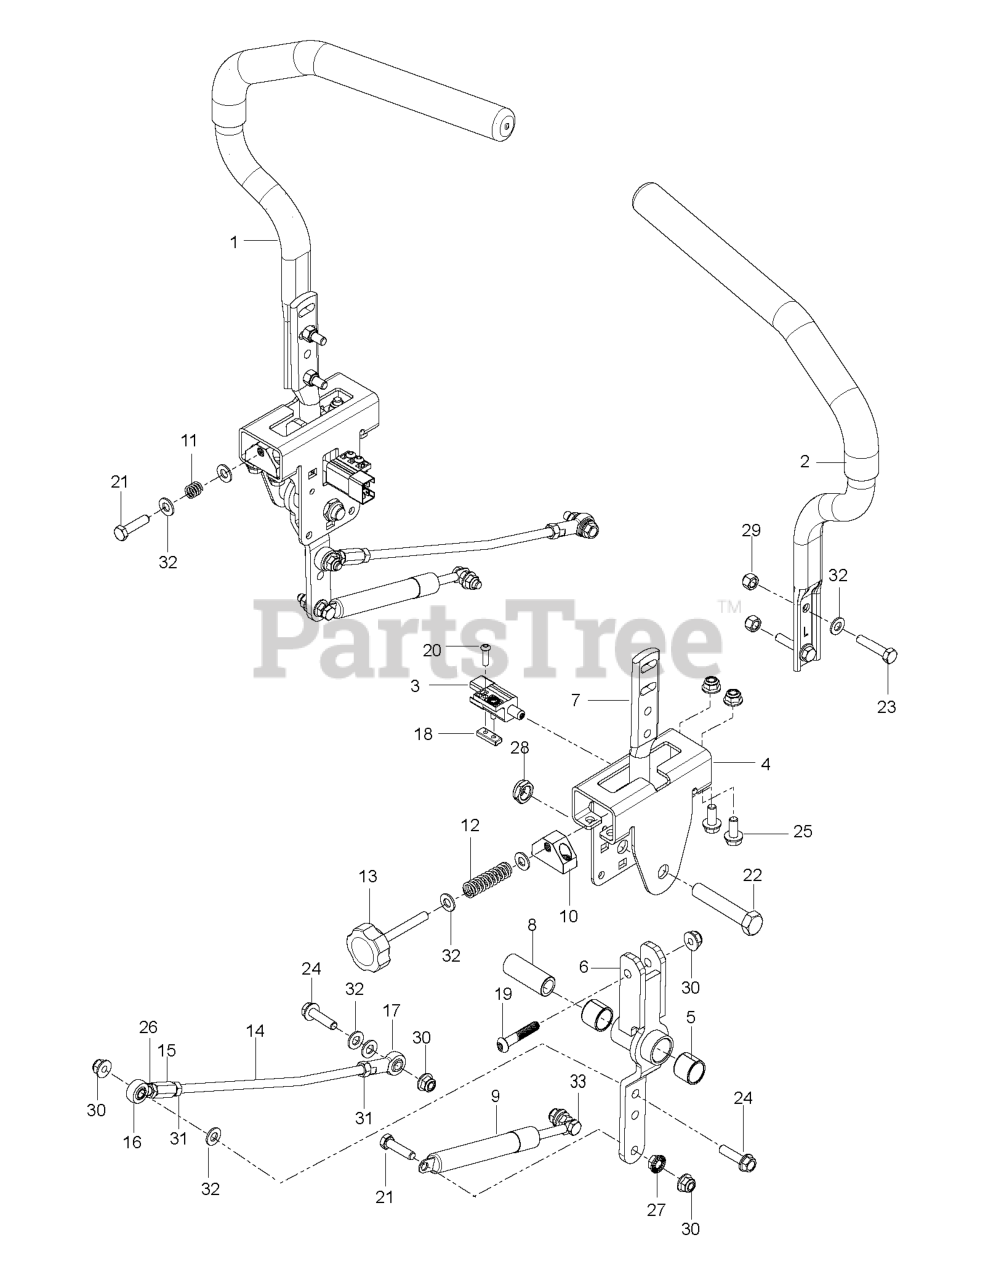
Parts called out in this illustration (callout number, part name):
1	TUBE.LEVER.CONTROL.ZTR.RT.428
1	LEVER.DRIVE.W/GRIP.RIGHT
1	LEVER.DRIVE.W/GRIP.LEFT
2	TUBE.LEVER.CONTROL.ZTR.LT.428
3	SWITCH INTERLOCKT
4	BRACKET, CONTROL
4	BRACKET.CONTROLS.ZTR.X431
5	BEARING, FLANGE
5	BEARING.PT.750
6	LEVER CONTROL PIVOT
6	CONTROL.WELDMENT.RZ
7	LEVER.HANDLE MOUNT
8	SPACER.PIVOT.CONTROL
10	BLOCK.TRACKING
10	BLOCK TRACKING CONTROL ZTR
12	SPRING COMPRESSION 2.0
14	ROD, CONTROL
15	ROD END COUPLER
16	ROD.END.MALE.LH.THREAD
17	RH ROD END
17	JOINT.HEIM.FEML.5/16.RH.THREAD
18	PLATE NUT ZTR
19	SCREW 5/16-18 X 1 3/4 BTN-HD
20	SCR #10-24 X .75 SKT HD BLK
21	BOLT.5/16-18X1-1/4 FULL.THREAD
22	HCS 1/2C X 2 3/4
22	HCS 1/2-13 X 2-3/4 GD 5 ZD
23	CAPSCREW 5/16 X 1/1/2 HEX HEAD
24	HHFS 5/16-18 X 1.25 TPBLT GD 5
25	HHFS 5/16-18 X 3/4
26	NUT 5/16F LEFTHAND
27	NUT 5/16C WHIZ
28	NUT 1/2-13 HEX JM NYL
29	NUT 5/16 NYLOC
30	5/16-18 NYLOC FLANGE NUT
32	WASHER
33	HCS 5/16C X 1 1/4
